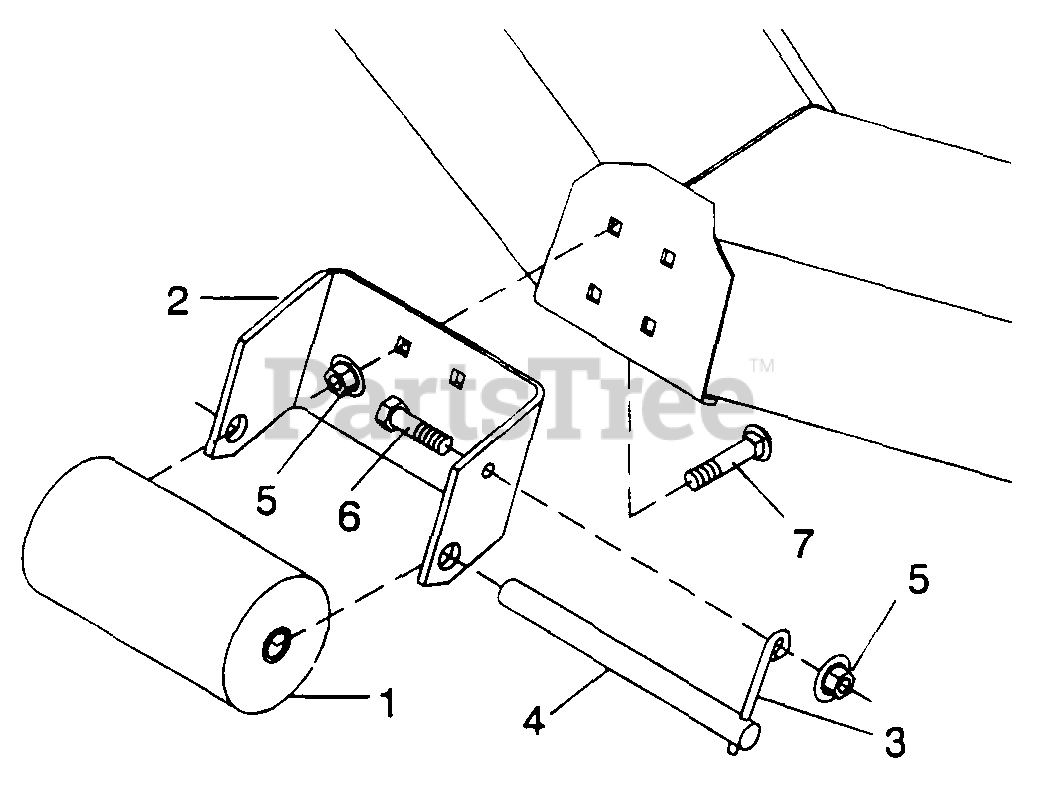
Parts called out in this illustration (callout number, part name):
1	Front roller
2	Roller bracket
3	.25 x 3.1 Retainer pin
4	Roller pin, drilled .75 x 8.6 x 9
5	3/8 NC Whiz nut
6	3/8 NC x 1 Hex head cap screw GR5
7	3/8 NC x 1 Carriage bolt GR5, plated
